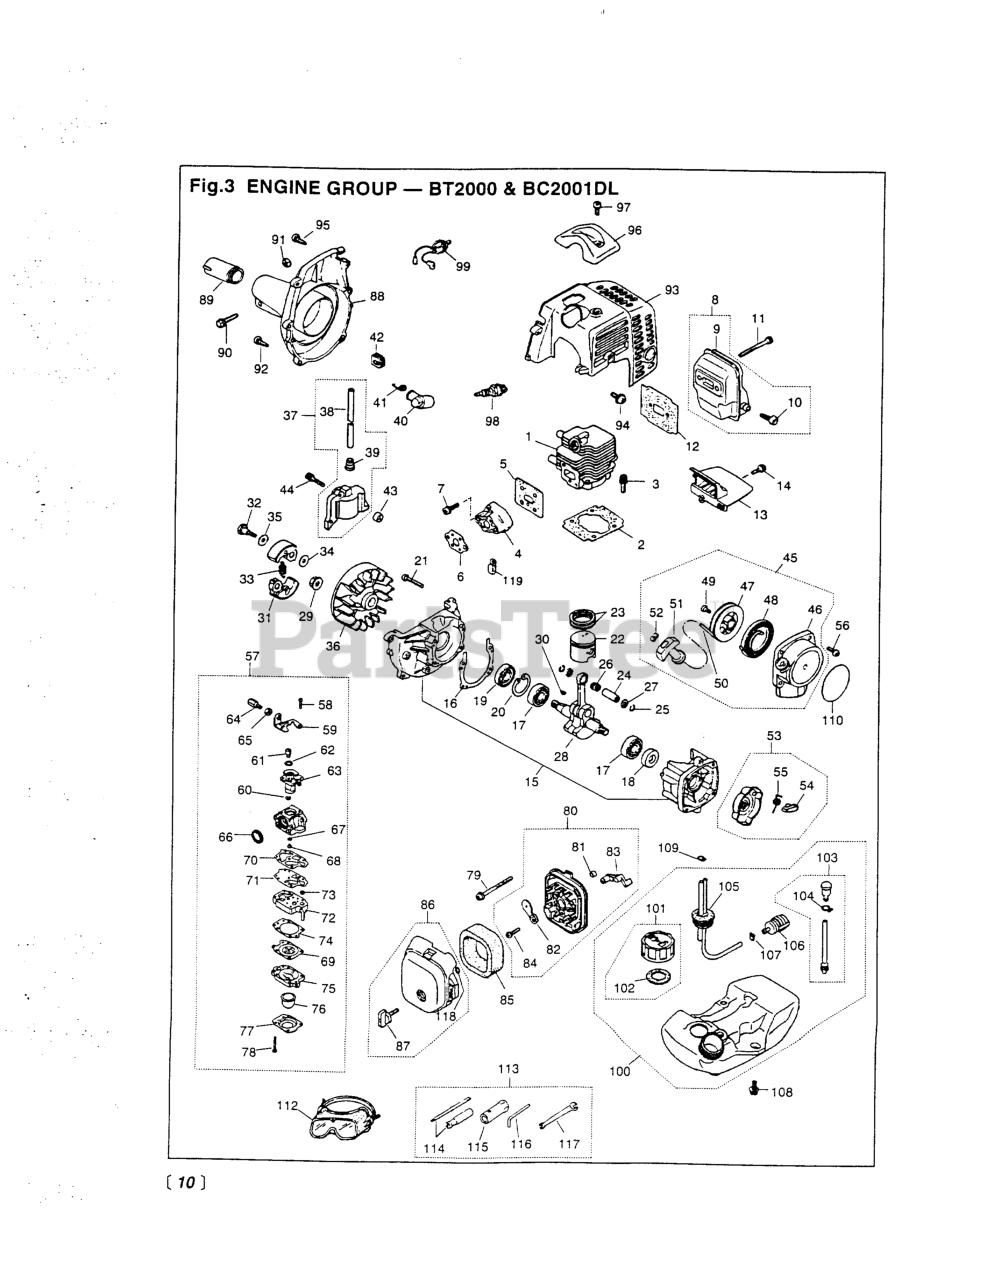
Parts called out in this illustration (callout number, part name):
1	CYLINDER
3	BOLT, M5 X 22
7	SCREW, M5X20 (RPLS.1400-75510)
9	MUFFLER ASSY (USE 5913-15100)
10	ARRESTER (RPLS 5850-15140)
11	BOLT, M5 x 50
12	GASKET, MUFFLER
14	SCREW, M4 X 16
15	CRANKCASE
17	BEARING
18	SEAL, OIL (RPLS 1100-21210)
19	SEAL, OIL (RPLS 1140-21220)
20	RING, SNAP, M28 x 1.2
21	BOLT, M5 X 30
22	PISTON (REPLACES 1140-41110)
23	RING, PISTON (RPLS 1850-41210)
24	PIN, PISTON 5x8x26
25	RING, SNAP (RPLS 1101-41320)
27	WASHER
28	CRANKSHAFT (RPLS 1850-42000)
30	KEY
32	BOLT
33	SPRING, CLUTCH (RPLS-51220)
34	WASHER, FLAT (USE 182303)
38	CORD
39	CAP
41	SPRING
42	GROMMET
43	SPACER (RPLS -71260)
44	BOLT
45	RECOIL ASSEMBLY
46	CASE
47	REEL
48	SPRING, SPIRAL
49	SCREW (RPLS -75150)
51	KNOB
52	PLATE, STOPPER
53	PULLEY ASSY (RPLS -75210)
54	RATCHET (RPLS 1850-75220)
55	SPRING, RETURN
56	SCREW, M4 X 16
57	CARBURETOR (RPLS-81000)
58	SCREW
60	RING
61	SWIVEL
62	WASHER
63	VALVE ASSY
64	SCREW, CABLE ADJUSTER
65	NUT, CABLE ADJUSTER
66	RING, PACKING
67	RING, O
68	JET
69	DIAPHRAGM (USE 4810-81260)
70	GASKET, PUMP
71	DIAPHRAGM
72	BODY, PUMP
74	GASKET, DIAPHRAGM
75	BODY, PURGE
76	PUMP, PRIMING
77	COVER, PUMP
78	SCREW
79	SCREW, M5 x 60
81	SLEEVE
82	PLATE, CHOKE (RPLS-82130)
83	LEVER, CHOKE
84	SCREW (REPLACES 50030272)
85	ELEMENT
88	HOUSING COMPLETE
90	BOLT, M6x35 (RPLS -50635)
91	NUT, M6 X 5
92	SCREW, M5X20 (RPLS.1400-75510)
94	SCREW, M5 x 12
95	SCREW, HOUSING
96	GUARD, PLUG
97	SCREW,M5 X 14 (RPLS 1400-15510
99	SWITCH
101	CAP (RPLS -85200)
102	PACKING
104	CLIP
105	PIPE COMPLETE
106	FILTER (RPLS 1850-85300)
107	CLIP (REPLACES 2841-31280)
108	SCREW
109	CLIP
113	TOOL SET
114	SCREWDRIVER
115	SOCKET, HEX, 3/4
116	BAR
117	SPANNER, 8 X 10 (RPLS 2540- )
118	RING
119	CLAMP
